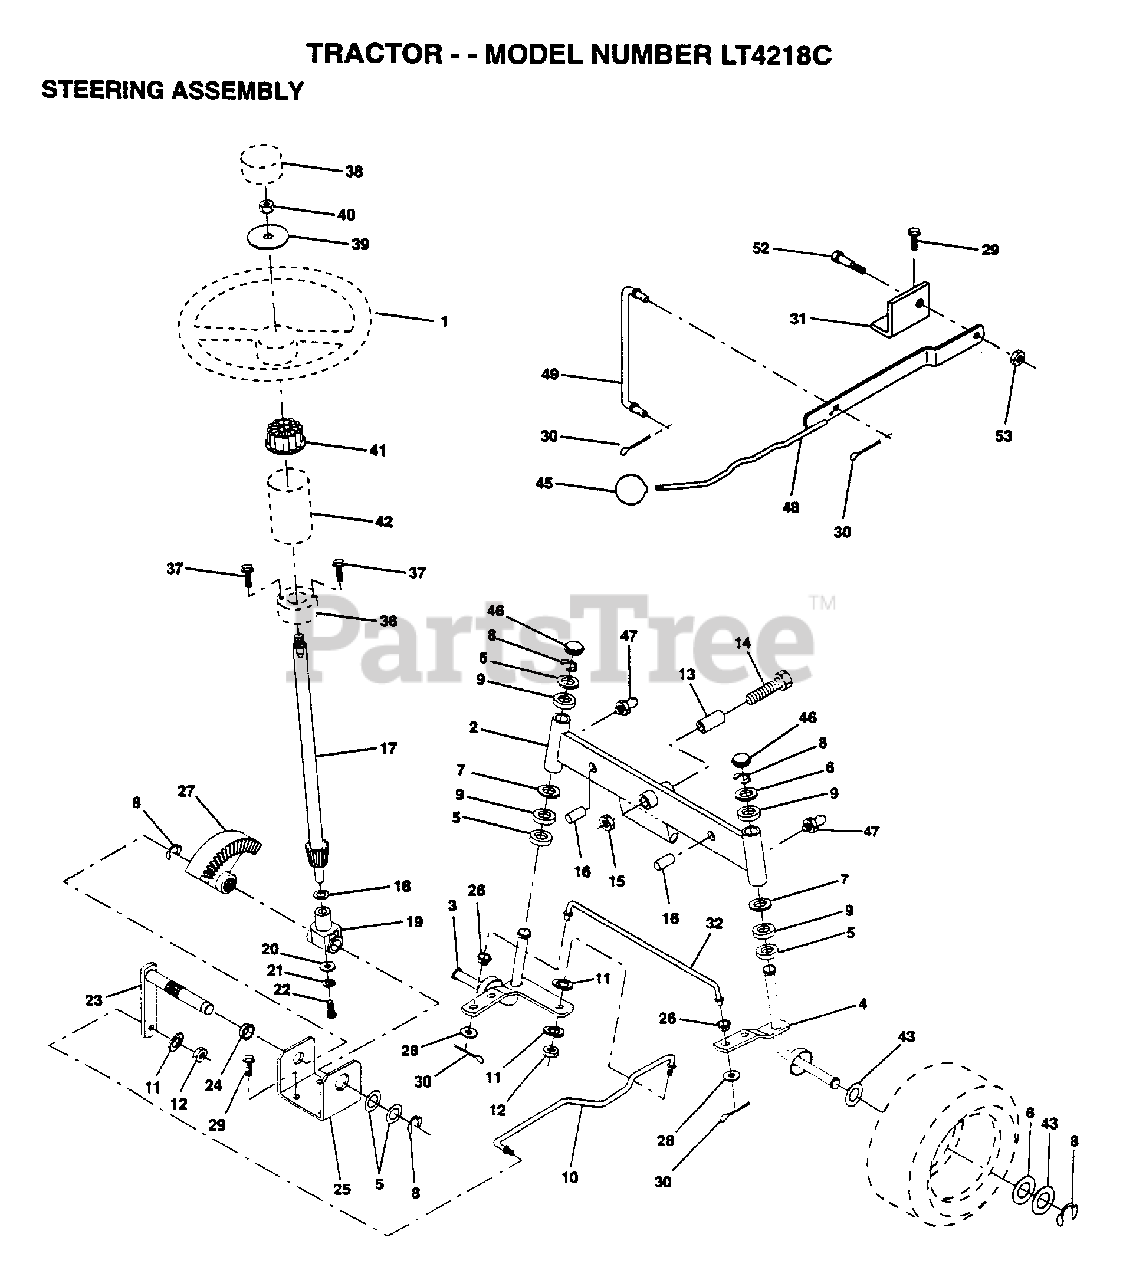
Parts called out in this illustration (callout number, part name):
2	AXLE ASM FRONT
3	SPINDLE LH
4	SPINDLE RH
5	WASHER .T
6	WASHER
7	WASHER
8	RING
9	COL. SRTG. BEAR.
11	LOCKWASHER
13	BEARING
14	BOLT HEX 5/8-11
15	"NUT-LOC,FLANGE LT"
16	AXLE PIN
17	STEERING SHAFT
18	THRUST WASHER
19	SUPPORT.SHAFT
21	LOCKWASHER
22	"SCREW,SPECIAL"
24	NYLINER T
25	"BRKT,STEERING"
27	GEAR SECTOR
28	WASHER
29	SCREW
30	COTTER PIN
31	BRKT.PVT.MAN.LVR.
32	TIE ROD
36	BUSHING.STRG.3/4
37	SCREW.10-24X1/2
38	BUSHING.STRG.3/4
39	WASHER
41	ADAPTER LT
42	BOOT SHAFT STEER
43	WASHER
45	KNOB T (1/2-HOLE)
46	CAP
47	ZERK M
48	LEVER.ASM.CLUTCH
49	LINK CLTCH W/NUTS
52	"BOLT, SHOULDER LT"
